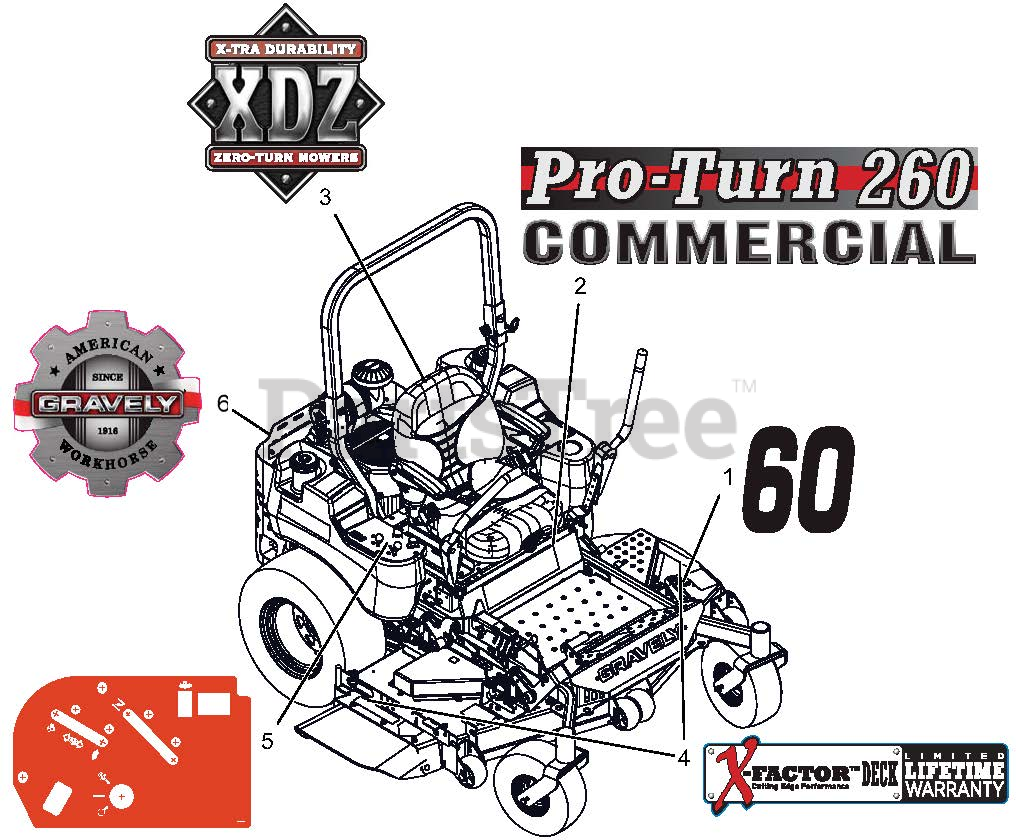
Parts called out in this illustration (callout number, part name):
1	DECAL, 60"
2	DECAL, PRO-TURN 260
3	DECAL, XDZ 5"
4	DECAL-X-FACTOR DECK
5	DECAL, CONTROL PANEL NON EFI
6	DECAL, GRAVELY HERITAGE-LARGE
